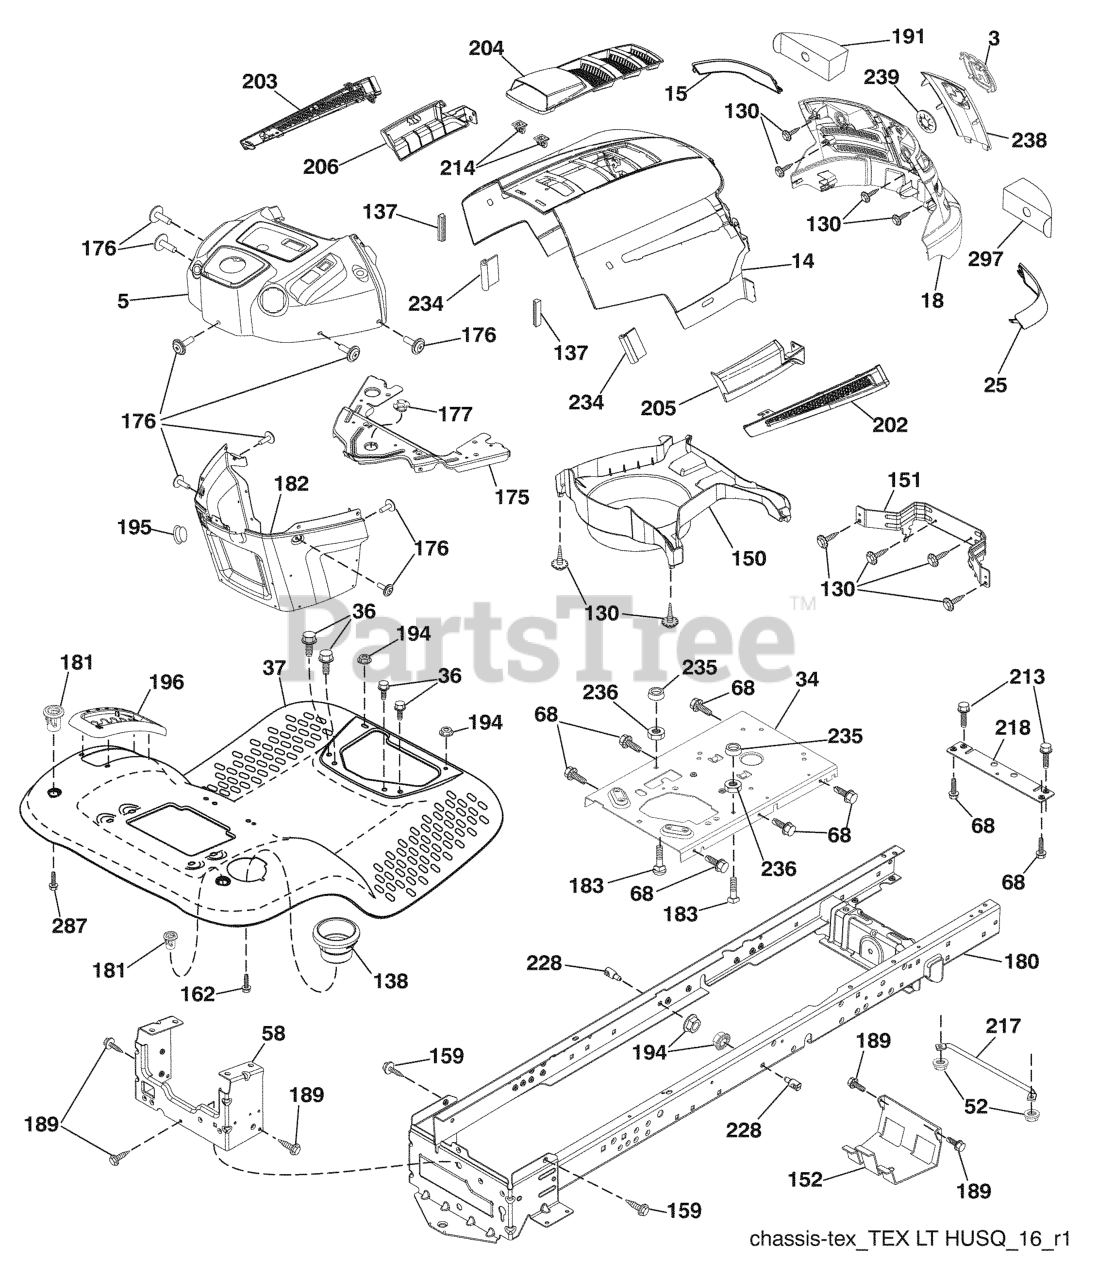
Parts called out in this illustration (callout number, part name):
3	RP LOGO
5	DASH
14	HOOD
15	LENS.HUSQVARNA LT.LH
18	RP GRILLE/LENS ASM.
25	LENS.HUSQVARNA LT.RH
34	PLATE.ENGINE.WELDED.CHASSIS
36	SCREW 5/16"
37	RP FENDER.TLT.FS.W/CPH.422
52	LOCKNUT
58	DRAWBAR UPPER 2PC SMALL FENDER
68	Screw THDROL 5/16-18 x 1/2
130	SCREW.#10 X 0.750.BOS
137	BUMPER DASH
138	CUPHOLDER.TL.TEX.418
151	BRACKET PIVOT
152	SHIELD.BROWNING.W/TEX
159	SCREW, 3/8-16X3/4
162	SCREW.HI-LO.CONSOLE
175	CROSSMEMBER
176	SCREW.#10-24X5/8.RN.QU
177	BUSHING STEERING
180	CHASS.WLDMNT.TL.12GA/2P.48/54
181	BUSHING.MNT.FEND.CRGO.
182	DASH.LOWER.PREDATOR LT
183	BOLT.5/16-18X1-1/4 FULL.THREAD
189	SCREW
191	INSERT REFLECTIVE
194	NUT LOCK HEX FLANGE 5/16-18
195	PLUG DASH
196	RP CONSOLE.ASM.DECKLFT.GR/RBT.
202	VENT SIDE HOOD RH
203	VENT SIDE HOOD LH
204	VENT TOP HOOD
205	SKIRT SIDE RH
206	SKIRT SIDE LH
213	BOLT
214	CLIP.RETAINER.TINNER.
217	ROD.PIVOT.HOOD
218	X-PIECE.HOOD.STOP.NON/
228	STUD.FASTNER.W/ANTI-ROTATE
234	BUMPER.HOOD.TEX.HUSQVARNA
235	SPACER FENDER
236	NUT.CENTERLOCK.5/16-
238	TRIM
287	SCREW 1/4X20
297	INSERT.REFLECTIVE.RH.
